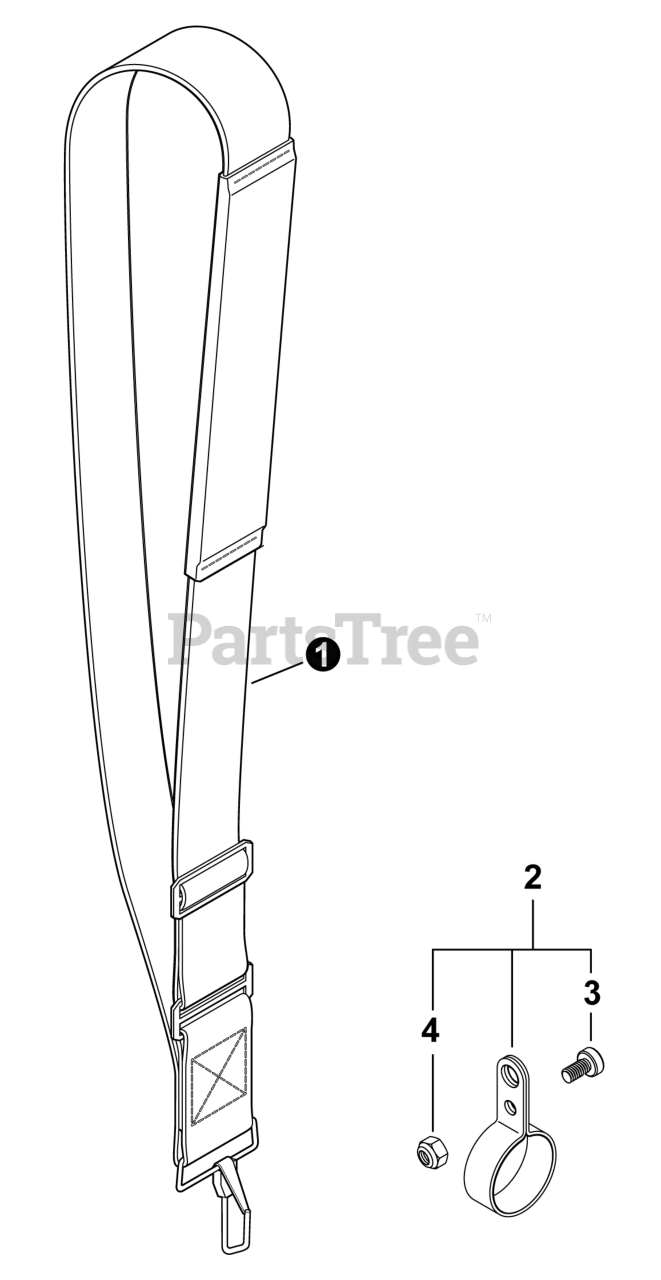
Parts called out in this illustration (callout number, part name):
1	STRAP ASSY, SHOULDER
2	HANGER KIT
3	BOLT, TORX 5x10
4	NUT, M5x8 NYLON INSERT
